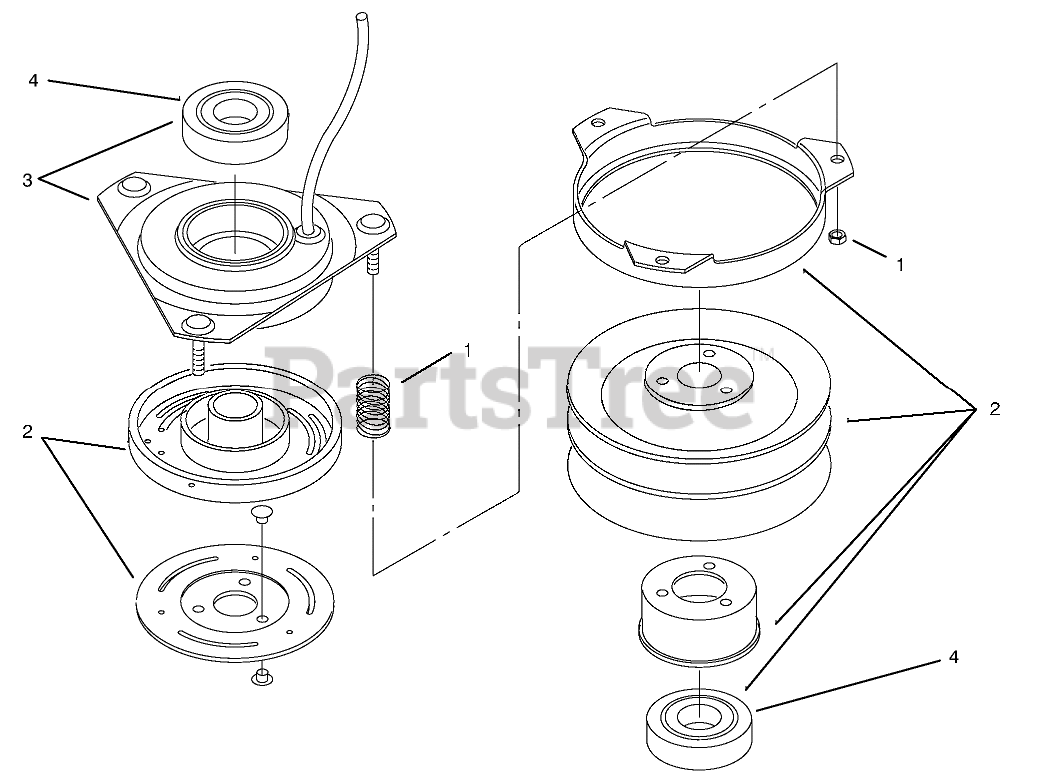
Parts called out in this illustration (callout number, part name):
1	ACCESSORY PKG SRVC PART
2	ASM - ROTOR/ARMATURE
3	FIELD ASSY (SRVC PART)
4	BEARING-ELEC CLUTCH
